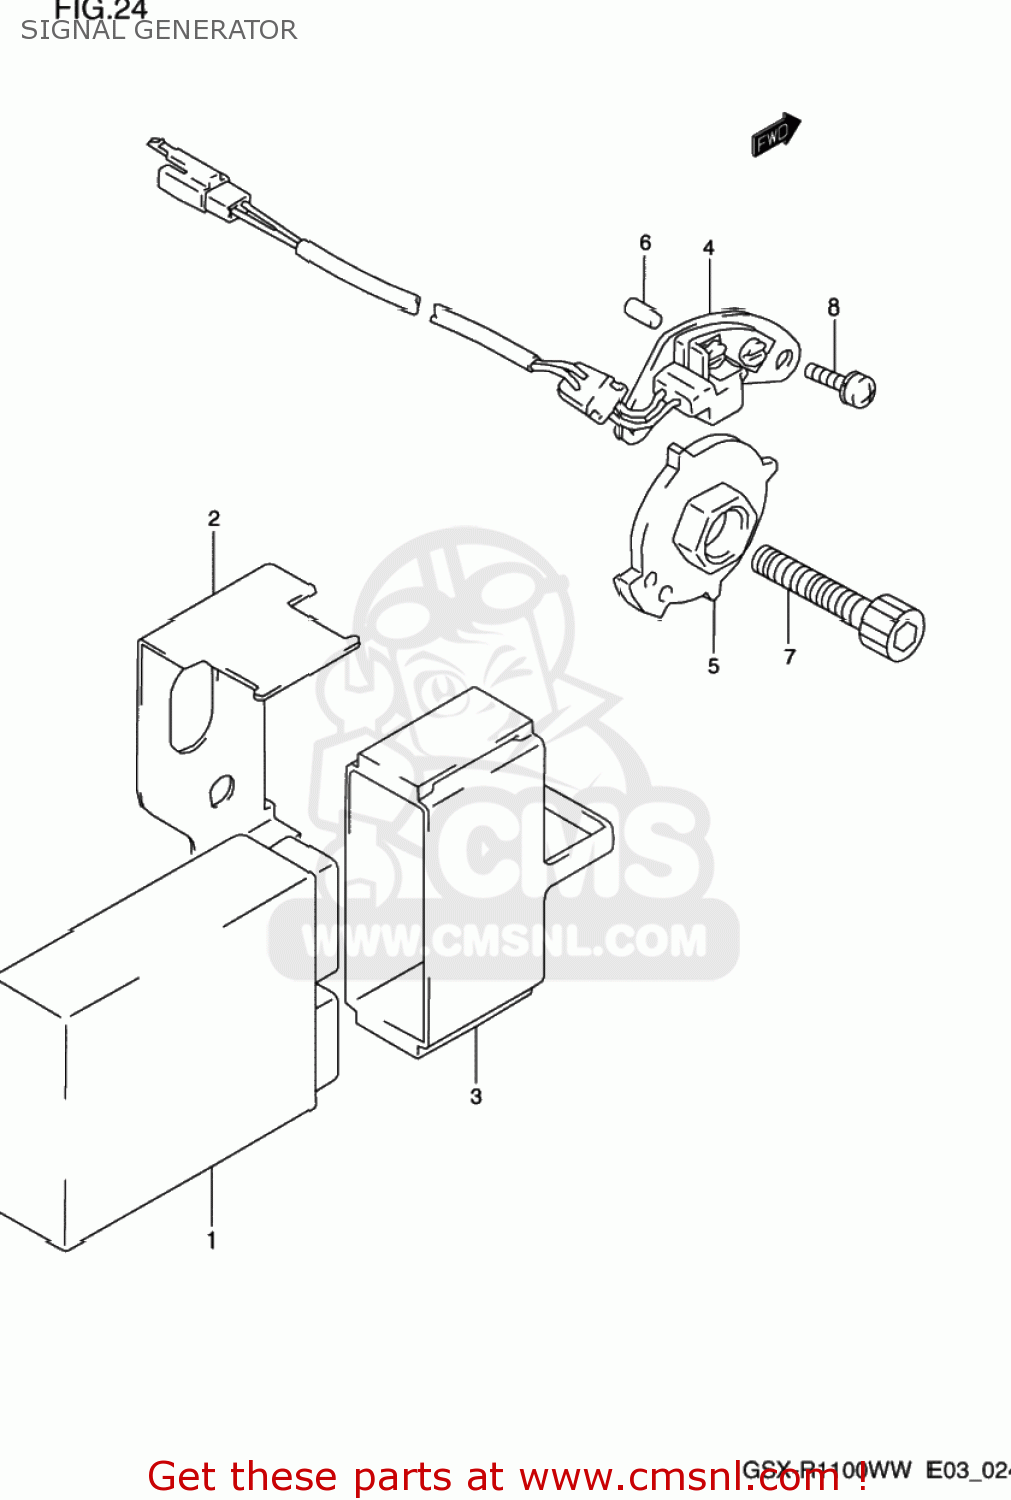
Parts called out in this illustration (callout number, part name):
1	IGNITER
2	BRACKET,IGNITOR
3	CUSHION,IGNITOR
4	STARTER,SIGNAL GENERATOR
5	ROTOR,SIGNAL GENERATOR
6	PIN
7	BOLT
8	SCREW
